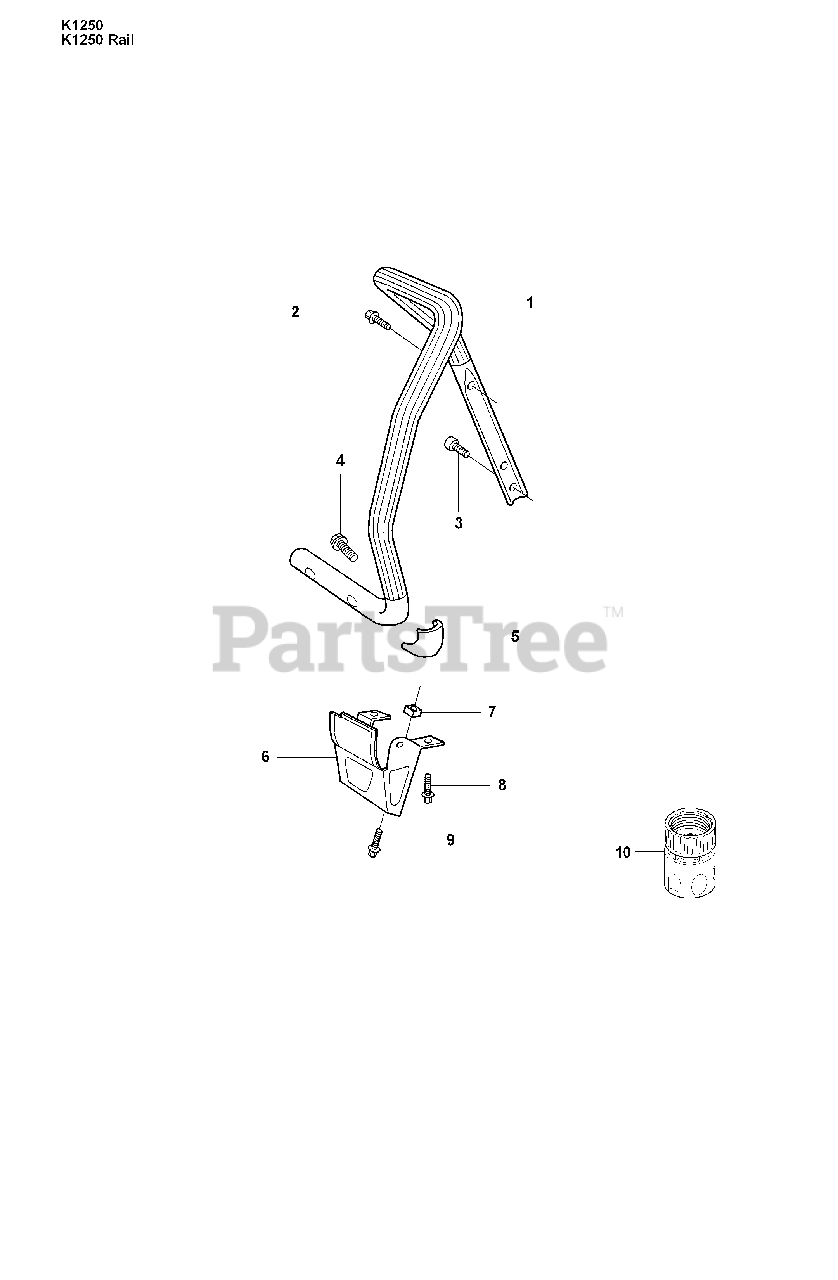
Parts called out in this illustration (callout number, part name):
2	SCREW
6	GROUND SUPPORT
10	COUPLER
